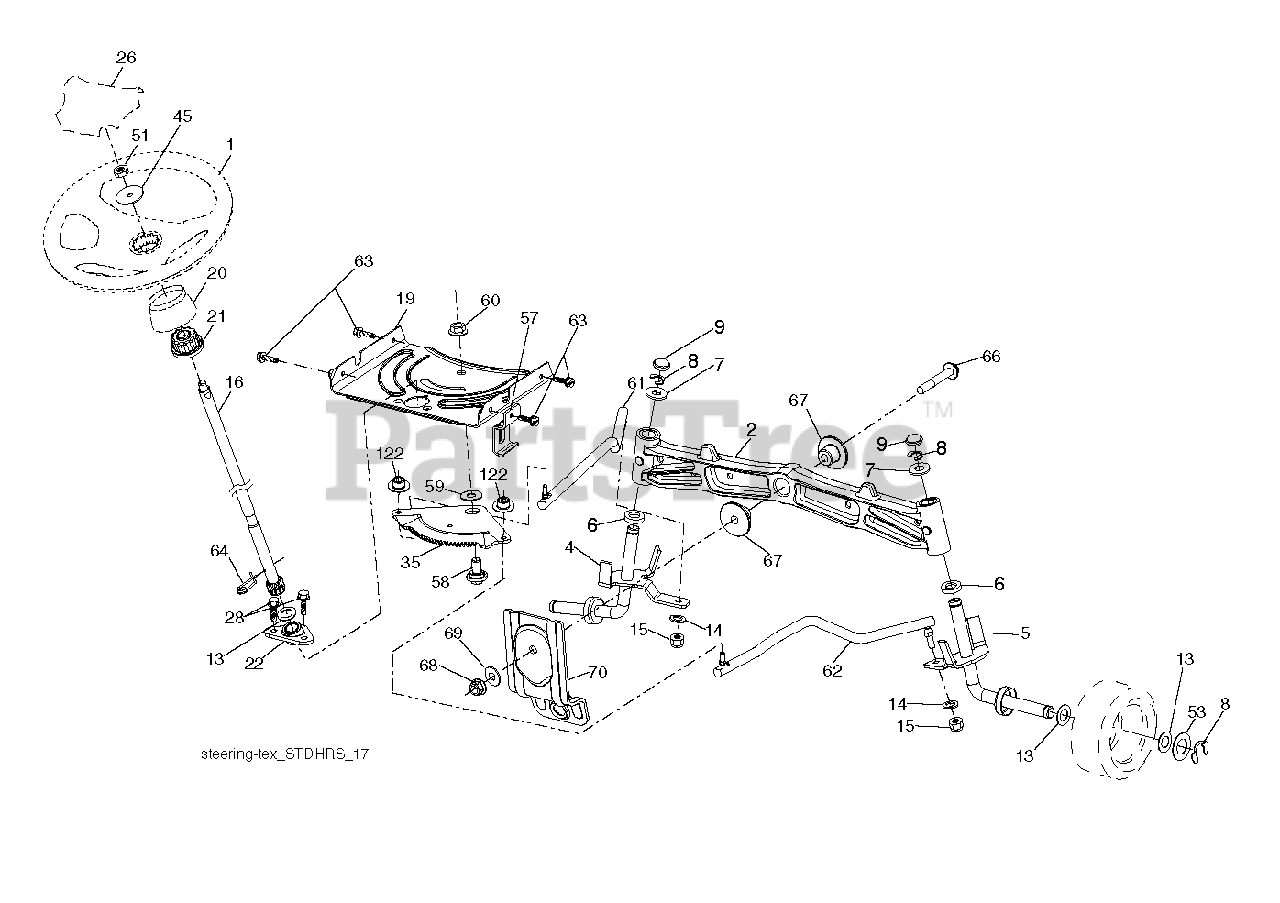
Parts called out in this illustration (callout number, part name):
1	WHEEL, STEERING
4	SPINDLE.WELDED.LH.15"T
5	SPINDLE.WELDED.RH.15"T
6	BRNG T
14	WASHER, LOCK 3/8
15	NUT CROWNLOCK 3/8-24
19	PLATE.STEER.DDL.NLT/NG
20	BOOT.STEERING.
21	ADAPTER, WHEEL STNG
22	STEERING.SUPT.LOWER.
26	INSERT, WHEEL STEERING
28	SCREW, 3/8-16X3/4
35	GEAR.SECTOR.PLATE.DDL.
57	BRKT.UPSTOP.GT/LT.TEX
58	BOLT.SHOULDER.SECTOR.P
59	WASHER.THURST.SECTOR.S
60	NUT FLANGE LOCK 5/8-11
61	DRAGLINK.LH.BALLSTUD.D
62	DRAGLINK.RH.BALLSTUD.D
63	SCREW
64	RETAINER.CLIP.SPRING.S
66	BOLT HEX FGHD 7/16-14 X 3 SERR
67	BUSHING.PM.FRONT AXLE
68	NUT.LOCK.FLANGE.7/16
69	WASHER.1.5X.505X.118
70	BRKT.DECK.SUSPENSION.F
